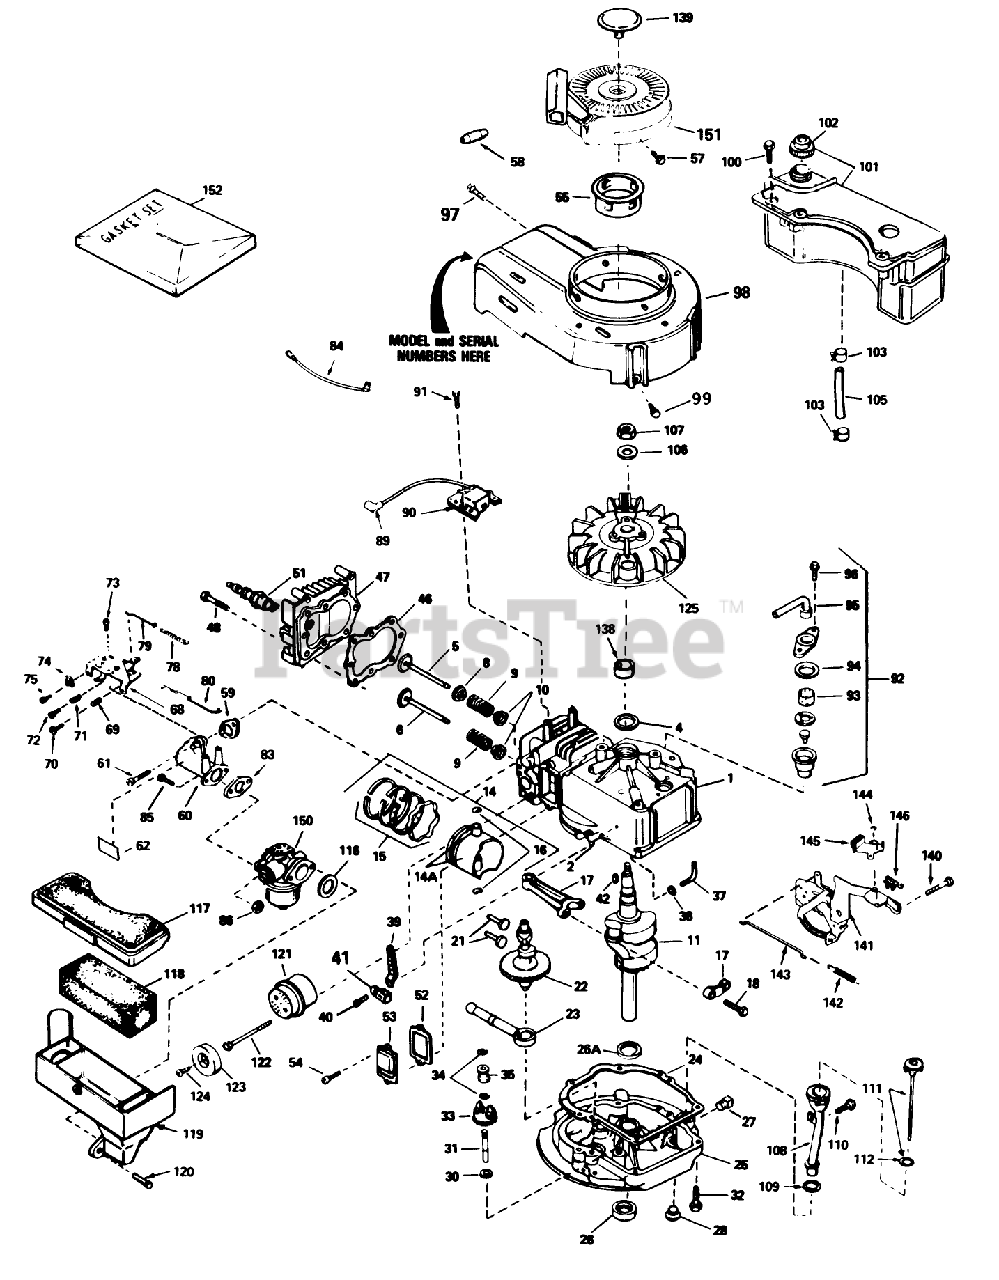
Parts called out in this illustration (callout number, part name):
1	Cylinder Assy. (Incl. #24)
2	Pin-Dowel
4	Seal-Oil
5	Valve, Intake (Std.) (Incl. Ref. #40)
5	Valve, Intake (1/32" oversize)(Incl. No. 40)
6	Valve, Exhaust (Std.)(Incl. No. 40)
6	Valve, Intake (1/32" oversize)(Incl. No. 40)
8	Seal Assy., Intake
9	Spring-Valve
10	Cap-Valve, Spring
11	Crankshaft
14	Piston, Pin Ring Assy. (Std.) (Incl. Ref. #13A, 14 15)
14	Piston, Pin Ring Assy. (.010 oversize) (Incl. Ref. #13A, 14 15)
14	Piston, Pin Ring Assy. (.020 oversize) (Incl. Ref. #13A, 14 15)
14A	Piston Pin Assy. (Incl . Ref. . #14) (Std.)
14A	Piston Pin Assy. (Incl. Ref. #14) (.010 Oversize)
14A	Piston Pin Assy. (.020 oversize) (Incl. Ref. #14)
15	Ring Set (Std.)
15	Ring Set (.020" OS)
15	Ring Set (.010" OS)
16	Ring-Retaining, Piston Pin
17	Rod Assy., Connecting (Incl. Ref. #17)
18	Bolt-Rod, Connecting
21	Lifter-Valve
22	Camshaft(Mech.Comp. Release)
23	Oil Pump ASM
24	Gasket
25	Flange-Mounting (Incl. Ref. #26, 27 39)
26	Seal-Oil
26A	Washer-Thrust
28	Plug Oil Drain
30	Washer-Flat
31	Shaft-Governor
32	Screw (1/4-20 x 1-1/4)
33	Governor Gear ASM
34	Ring-Retaining
35	Spool-Governor
37	Rod, Governor (Incl. No. 36)
38	Washer-Flat
39	Governor Lever
40	Screw
41	Clamp-Lever, Governor
42	Key-Flywheel
46	63573 GIL 42 SNWTHW
47	Head-Cylinder
48	Screw (5/16-18x1-1/2)
51	Plug, Spark (Autolite 458, Champion J-19LM or equiv.)
52	Gasket-Breather
53	Cover-Valve
54	Screw
55	Hub-Starter
57	Screw, Hex Hd.
58	Retainer-Starter Rope
59	Gasket-Intake
60	Pipe-Intake (Incl. Ref. #59)
61	Screw (1/4-20 x 1)
62	Decal-Primer
68	Control Assy.-Remote Speed (Incl. Ref. #69 thru 72 76)
69	61709/GIL1515A/95-5
70	Screw
71	Spring-Compression
72	Screw
73	Screw (10-24 x 9/16)
74	Conduit
75	Screw (10-32 x 3/8)
78	Spring Governor
79	2035A67 ADD.ASSEMBL
80	Link-Throttle
83	Gasket
84	Ground Wire
86	Nut and Lock Washer (1/4-28)
89	Cover-Spark Plug
90	Solid State
91	Screw
92	Breather Assy. (Incl. Ref. #46 thru 51)
93	Element-Breather
94	Gasket-Breather
95	Tube, Breaker
96	Screw (10-24 x 9/16)
97	Screw (10-24 x 9/16)
98	Housing-Blower
99	Screw (1/4-20 x 1/2)
100	Screw (10-32 x 35/64)
101	Tank Assembly-Fuel (Incl. Ref. #102)
102	Cap-Fuel
103	Clamp-Line, Fuel
105	Line-Fuel
106	Washer-Belleville
107	Nut-Flywheel
108	Tube-Oil Fill
109	Gasket
110	Screw (10-32 x 1/2)
111	Dipstick-Oil (Incl. Ref. #112)
112	O-Ring
116	Gasket-Cleaner, Air
117	Cover-Air Cleaner
118	Filter-Air Cleaner
119	Body Air cleaner
120	Screw
121	Muffler (Incl. Ref. #122)
122	Screw
123	Cover-Muffler
124	Screw (8-32 x 3/8)
125	Flywheel
138	Spacer
139	Plug Starter
140	Screw (1/4-20 x 3/8)
141	Bracket-S.E. Brake
142	Spring-Extension
143	Link-Control
144	Ring-Retaining
145	Lever-Brake
146	Terminal
150	Carburetor (Incl. Ref. #83)
151	Starter-Rewind
152	Gasket Set
